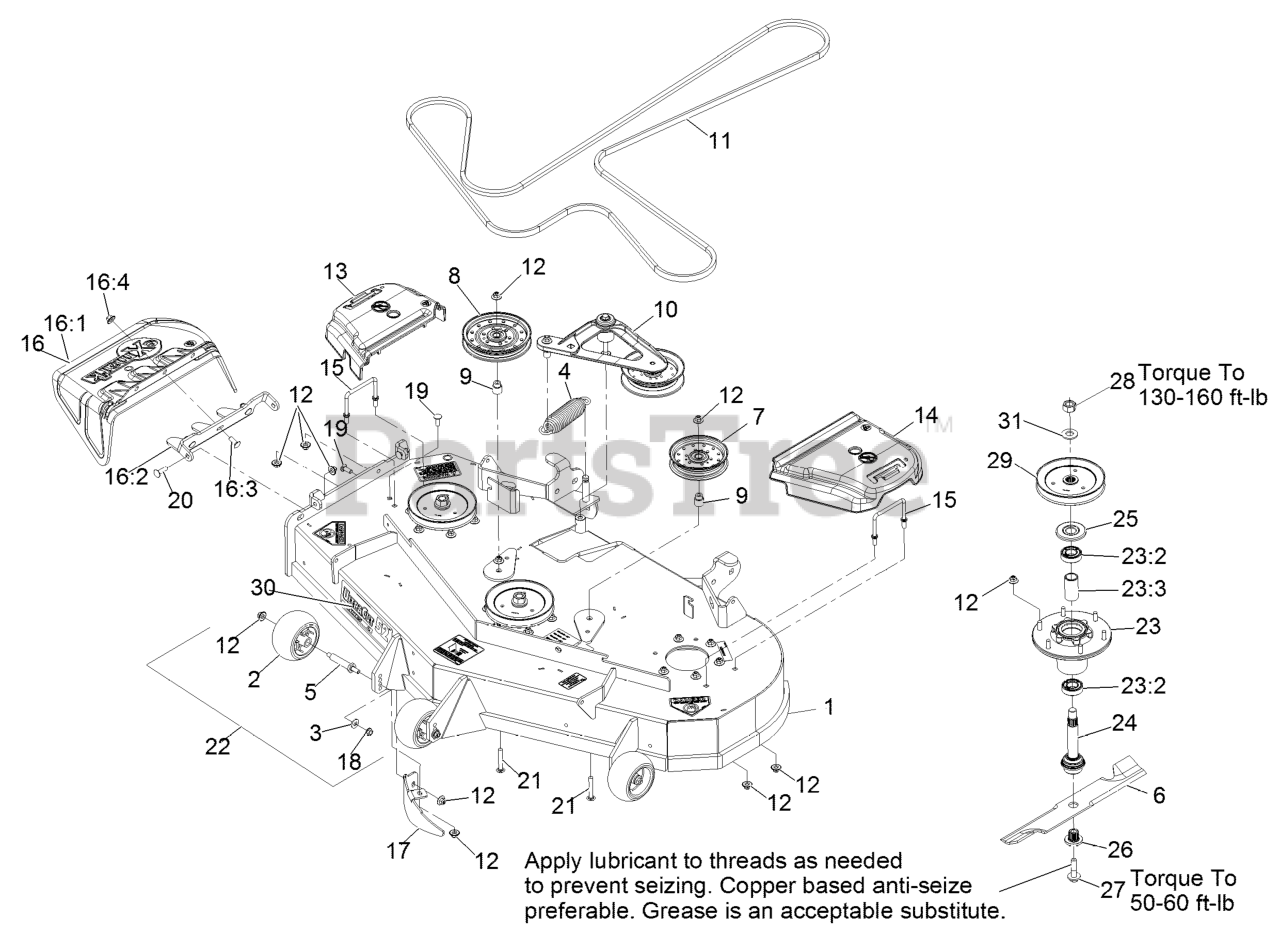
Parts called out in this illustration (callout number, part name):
1	ASM,DECK W/ DECALS 52
2	ROLLER-SCALP, ANTI
3	WASHER-BELLEVILLE
4	SPRING-EXTENSION
9	BUSHING-IDLER
10	DECK IDLER ASM
11	BELT,V-B X 186.00"
12	Nut-Nyloc 3/8-16 Flg
13	COVER-BELT, RH
14	COVER-BELT, LH
15	WIREFORM-COVER
16	ASM,DISCHARGE CHUTE
16:1	CHUTE,DISCHARGE
16:2	BRACKET,DISCHARGE CHUTE
16:3	SCREW-CARR
16:4	Nut-Nyloc 3/8-16 Flg
17	BAFFLE-DOGLEG, LZ-VT52
18	NUT-HHF, WHIZ
19	SCREW-CARR
20	Bolt-Carriage 3/8-16 X 1 1/4
21	SCREW-CARR
23	ASM-CUTTER HSG WITH BEARINGS
23:2	BEARING-BALL
23:3	SPACER-BEARING
24	ASM-SPINDLE AND SEAL
25	GUARD,BEARING TOP .989
26	BUSHING,SPLINED
27	SCREW,SEMS 1/2-20 X 2.19
28	NUT-HEX
29	SHEAVE,BLADE DRIVE 6.50
30	DECAL,ULTRACUT 52 SERIES
